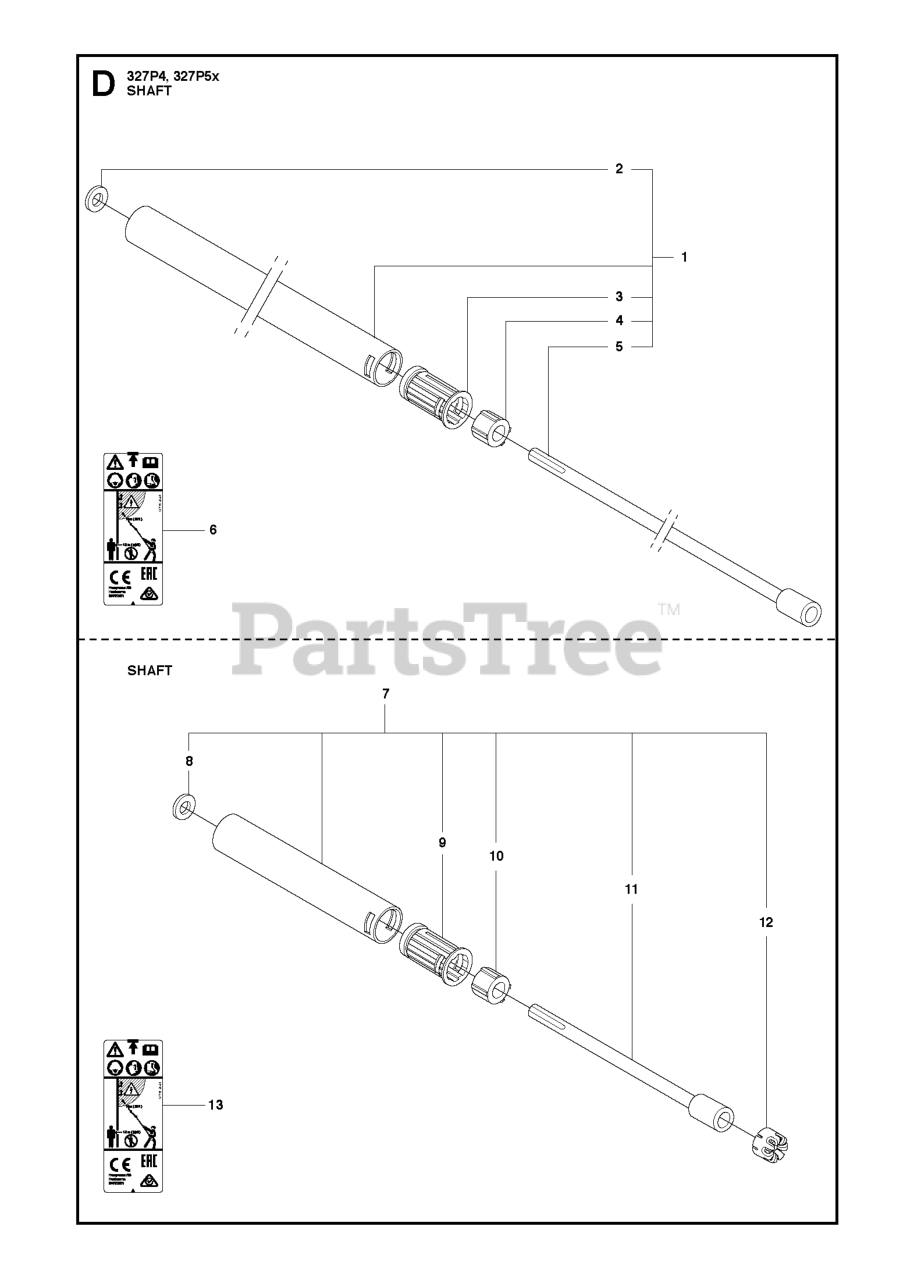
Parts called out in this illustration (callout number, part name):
1	TUBE
5	SHAFT
6	DECAL WARNING SPARK ARRESTOR
7	TUBE
11	SHAFT
13	DECAL WARNING SPARK ARRESTOR
